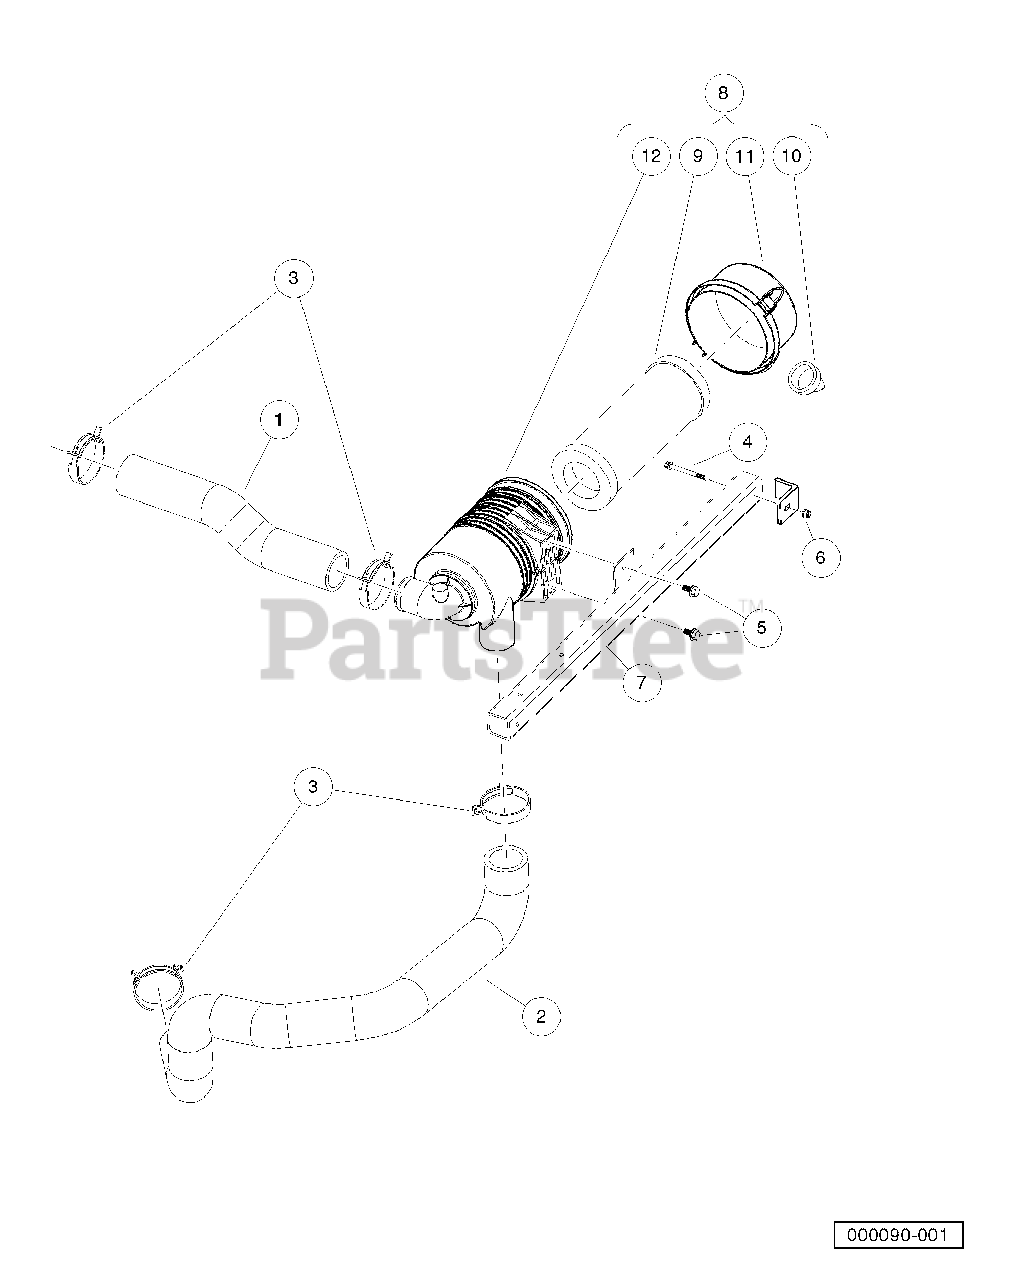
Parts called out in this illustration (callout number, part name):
1	Hose, Intake, GX620
2	Hose, Intake, Primary
3	Clamp, Hose, Ctb 64mm
4	Bolt, M 6 X 1.0 X 65 Hex, Flange, Head, Black
5	Bolt Flanged Head, M8 X1.25x 16 with Loctite
6	Nut Flg, M6 X 1.0 Nylon
7	Weldment, Support, Air Cleaner
8	Filter, Air, Canister, W/labe
9	Element, Filter, Air, 5 In
10	Valve, Evacuator, Filter Air
11	Cap, Latch Lock, Filter, Air
12	Body, Canister, Filter, Air
